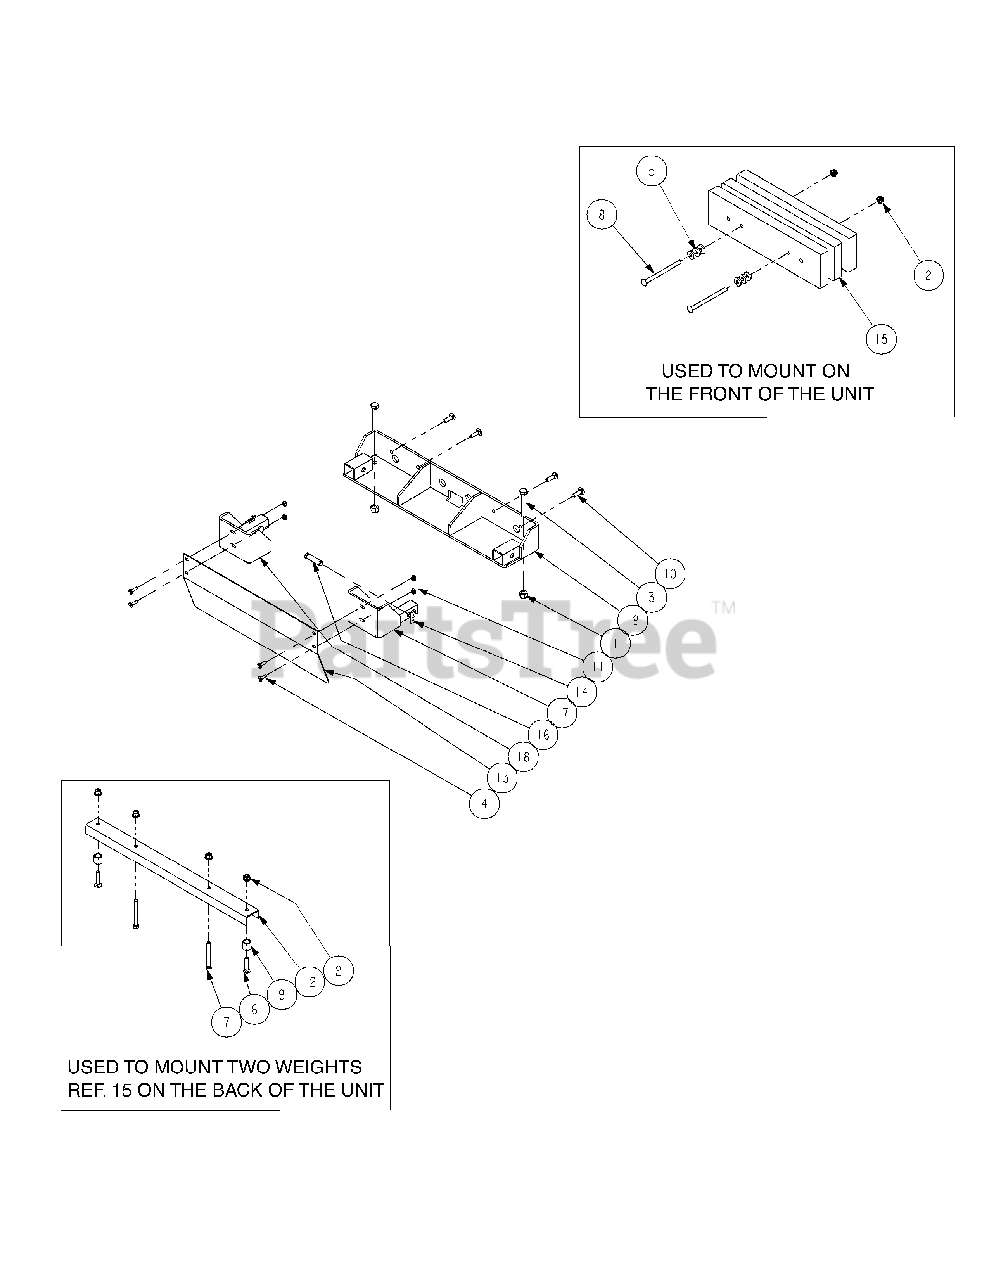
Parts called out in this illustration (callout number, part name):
1	Nut, 1/2-13, Nylon Insert
2	Nut, 3/8-16, Flange Lock
3	HHCS, 1/2-13 x 3.00
4	Carriage Bolt, 1/4-20 x 1.00
5	Washer, .390 ID x 1.0 OD x .180
6	Carriage Screw, 3/8-16 x 1.75
7	HHCS, 3/8-16 x 3.25
8	Carriage Bolt, 3/8-16 x 5.50
9	Spacer, .635 ID x .86 Long
10	Carriage Screw, 3/8-16 x 1.25
11	Nut, 1/4-20, Flange Lock
14	Hair Pin, 1/8
16	Clevis Pin, 1/2 x 2.00 Long
17	Support Weldment, Left
18	Support Weldment, Right
